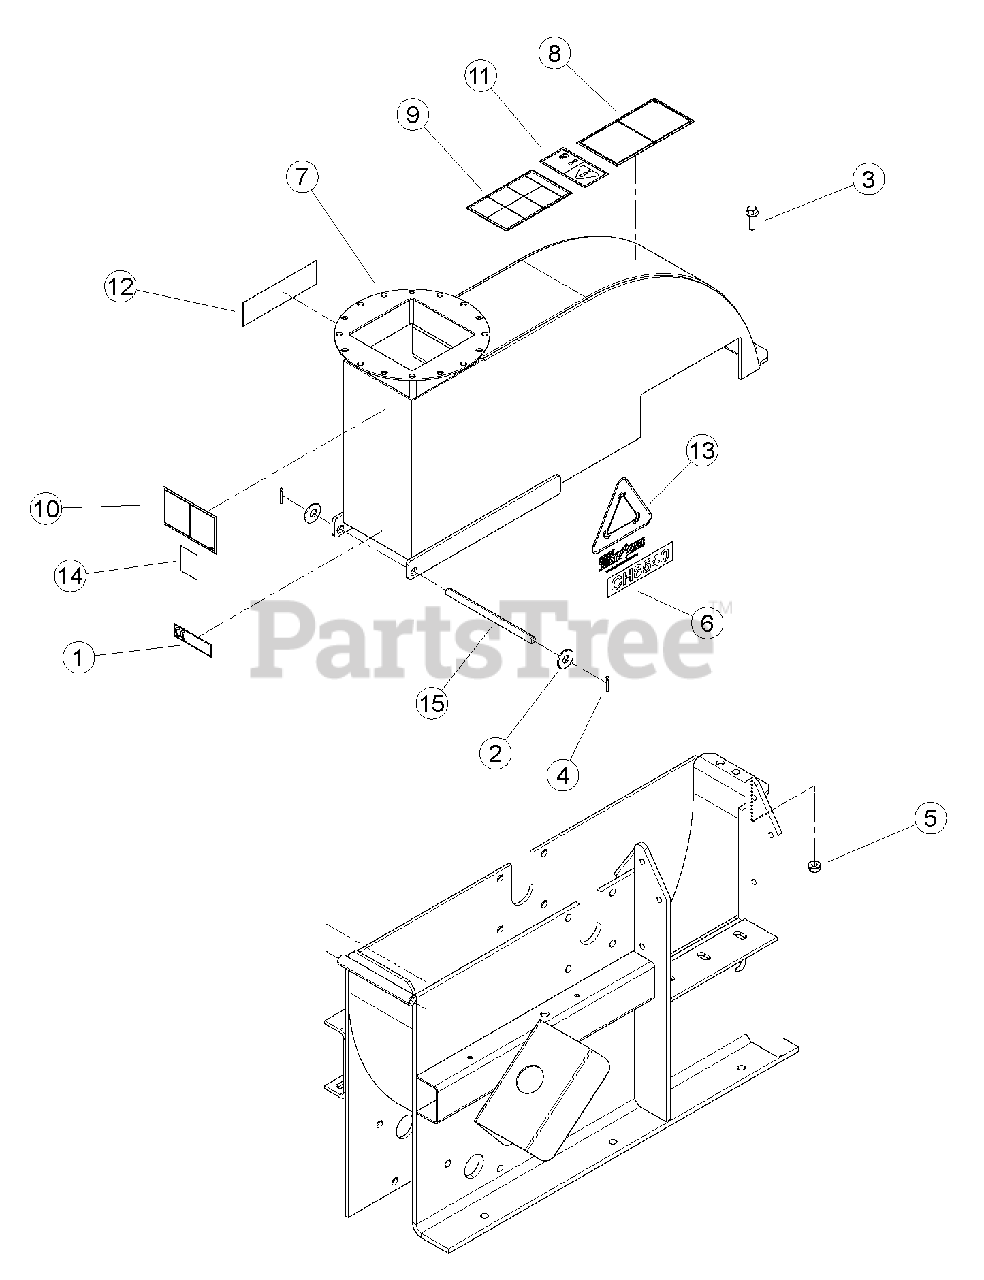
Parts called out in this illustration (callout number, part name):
1	DECAL, CH8540 INFORMATION (CE COMPLIANT ONLY)
2	WASHER, 1/2" FLAT ZP
3	BOLT, 3/8 X 1-1/4 FLANGE NC
4	PIN, 1/8 X 1.00 ZP COTTER
5	NUT, 3/8-16 NYLOCK FLANGE
6	DECAL, MODEL CH8540
7	ASSEMBLY, CHIPPER COVER W/ DECALS
8	DECAL, KNIFE ACCESS ISO
9	DECAL, OPERATING INSTRUCTIONS ISO
10	DECAL, DISCHARGE ISO
11	DECAL, MAINTENANCE ISO
12	DECAL, ECHO BEARCAT 6.82 X 1.90
13	DECAL, CHIP IT
14	DECAL, ECHO BEARCAT QR CODE
15	SHAFT, CHIPPER TOP PIVOT
